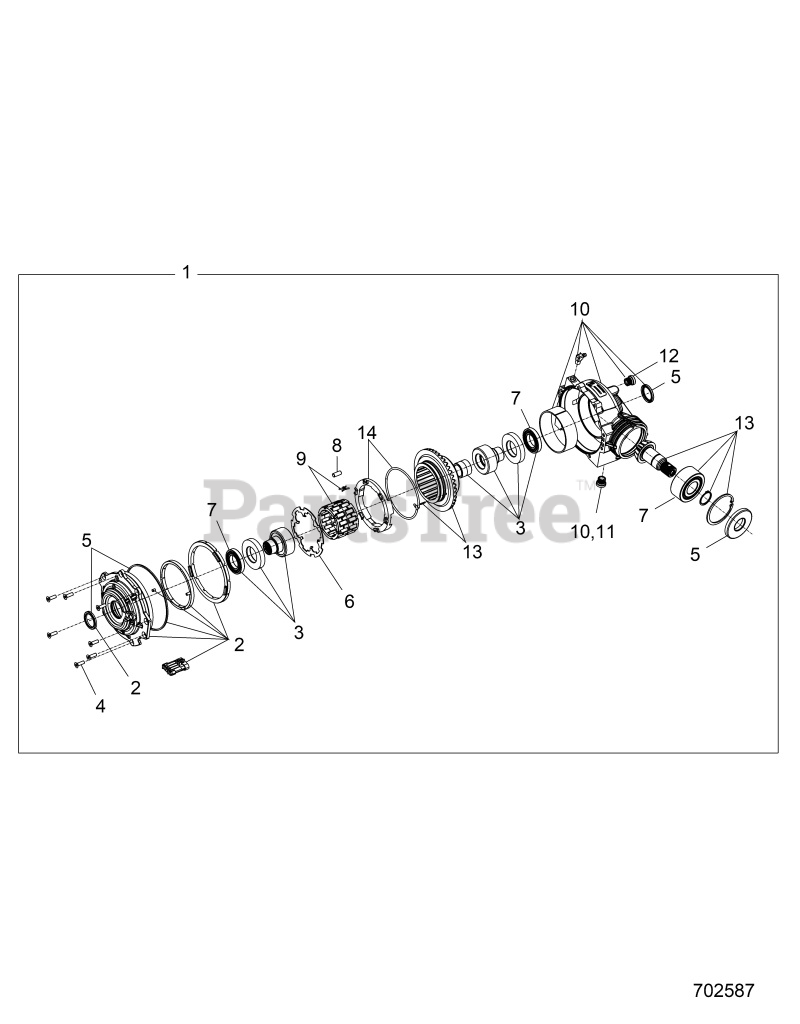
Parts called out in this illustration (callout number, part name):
1	ASM-GEARCASE,FRONT,5
2	ASM-COVER,OUTPUT
3	KIT-HUB,ASM
4	KIT-FASTENER
5	KIT-SEAL REPAIR
6	PLATE-4WD ARMATURE
7	BEARING-PINION,5306
8	K-CLUTCH ROLLS
9	ASSY, ROLL CAGE ZN
10	KIT, GEARCASE ASSY
11	DRAIN PLUG(6203-95-010)
12	FILL PLUG(1300-04-001-T)
13	ASM. GEAR HOUSING AND PINION GEAR
14	K-TORSION SPRING & RETAINER
